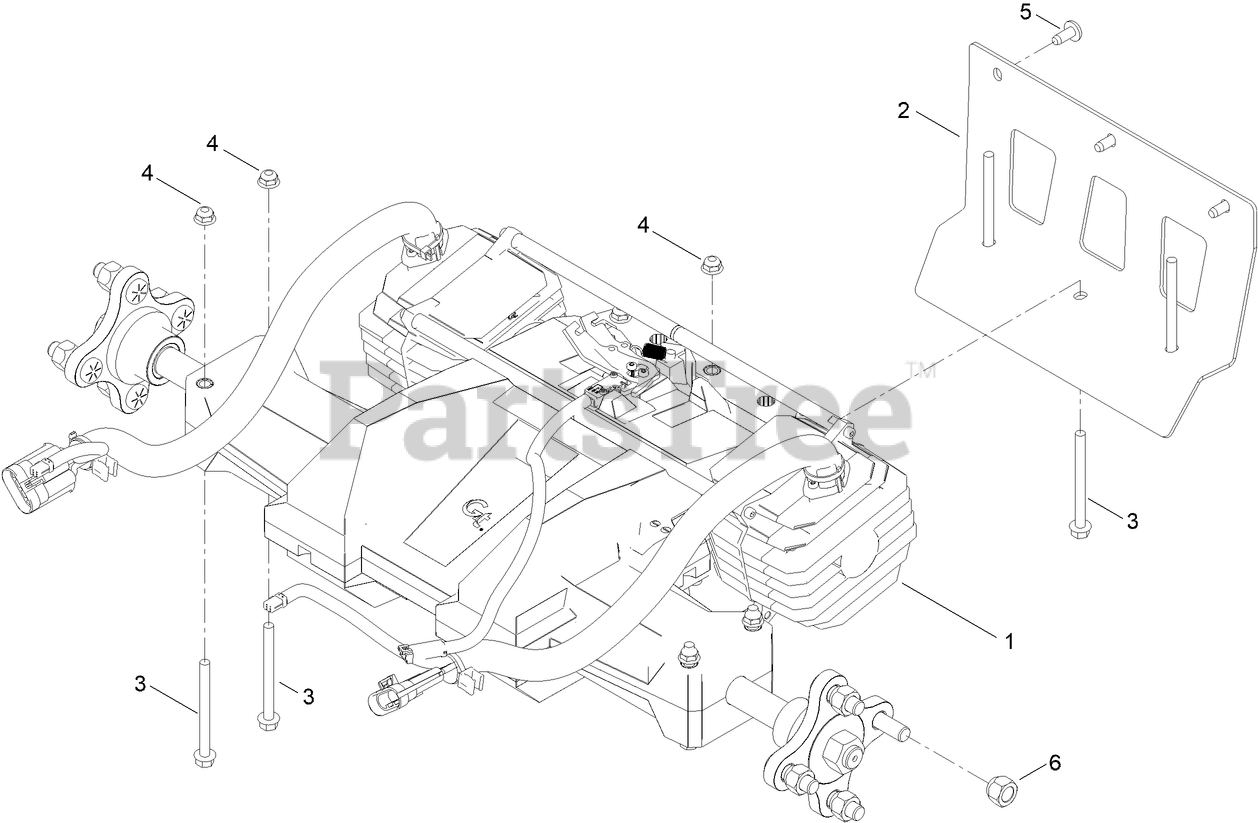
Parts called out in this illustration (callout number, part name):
1	TRANSAXLE-ELECTRIC, 18"
2	BRACKET-TRANSMISSION
3	SCREW-HH
4	NUT-HF
6	NUT-LUG
